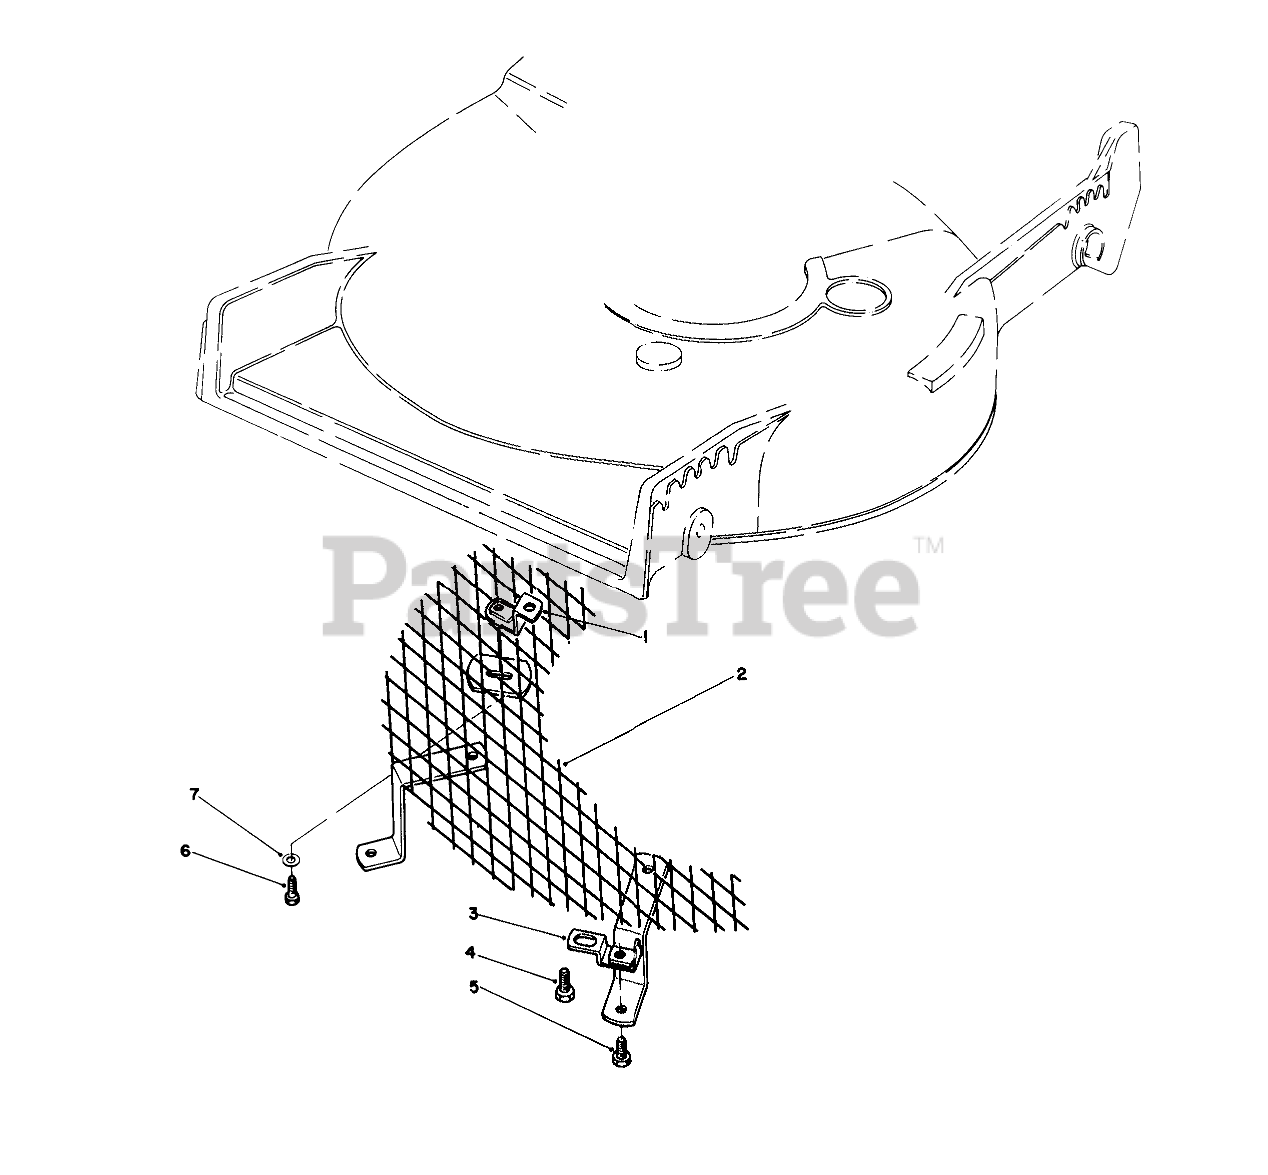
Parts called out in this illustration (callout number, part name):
1	BRACKET WA
2	SCREEN WA
3	MTG. BRACKET W.A.
4	SCREW-HWHTF
5	SCREW-HH
6	SCREW-HH
7	WASHER-FLAT
